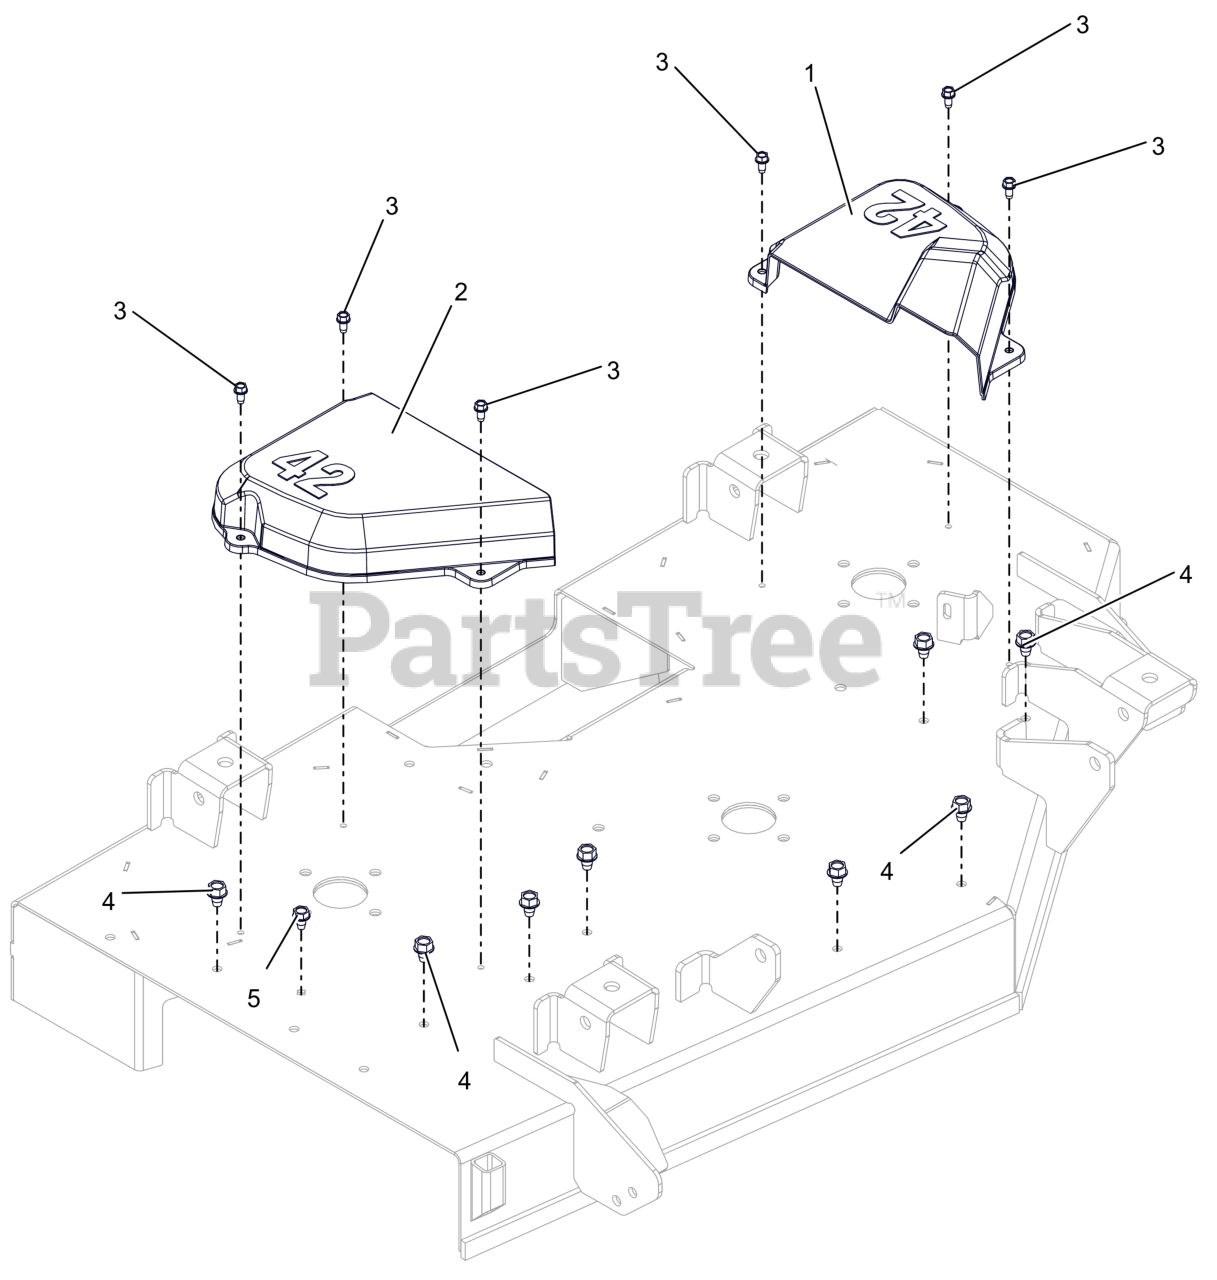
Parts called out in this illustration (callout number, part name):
1	COVER, BELT 42" LH
2	COVER, BELT 42" RH
3	SCR-TAP .25-20X.50 HWH ZCC
4	SCR,TAP .375-16X.50 HWH TR ZCC
5	SCR,TAP .312-18X.50 HWH TR ZCC
